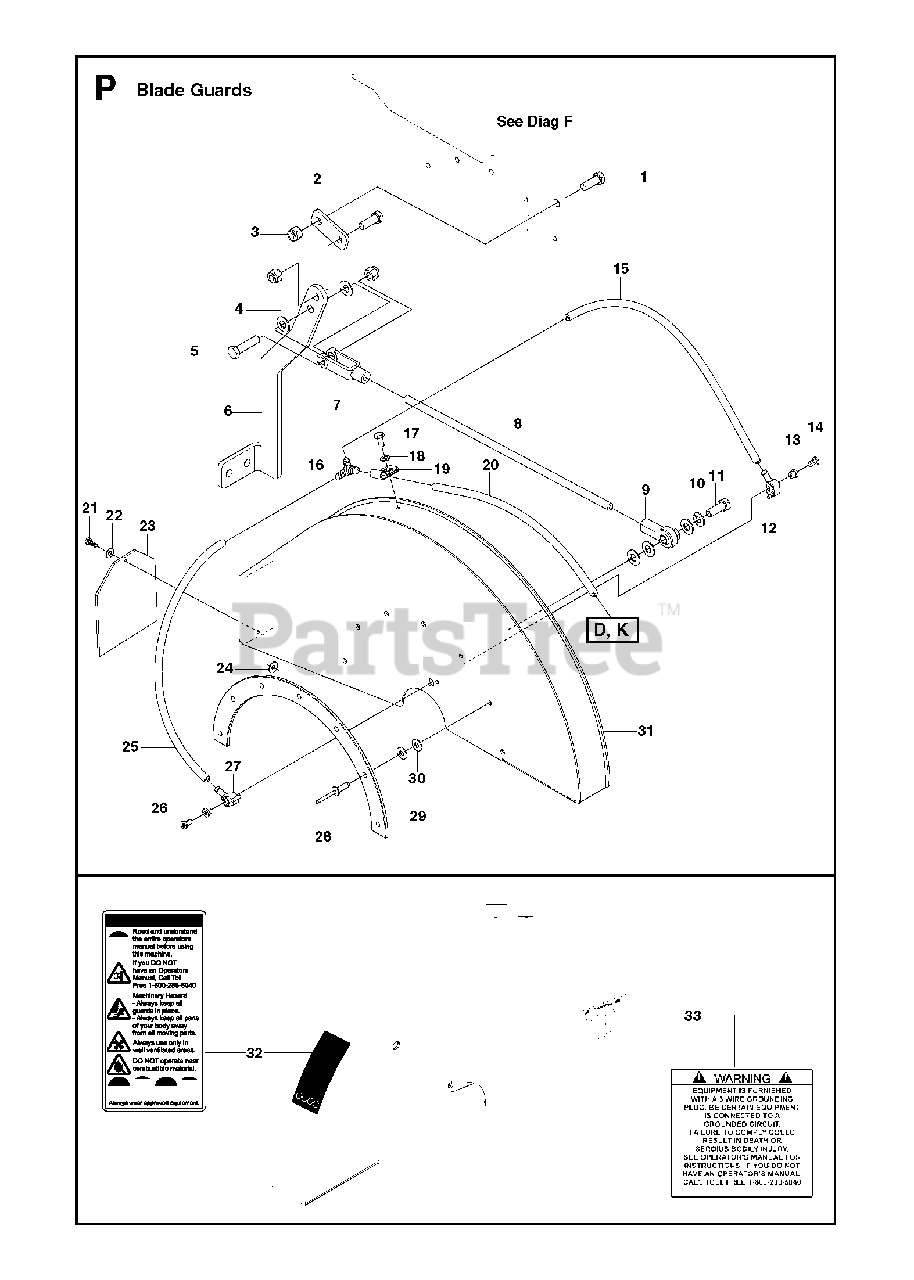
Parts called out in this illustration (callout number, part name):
3	NUT
4	WASHER
10	WASHER
14	SCREW ITXSCM
17	HCS ¼-20 X ½ GR 5 ZD
20	HOSE
30	WASHER 1/4 SAE
